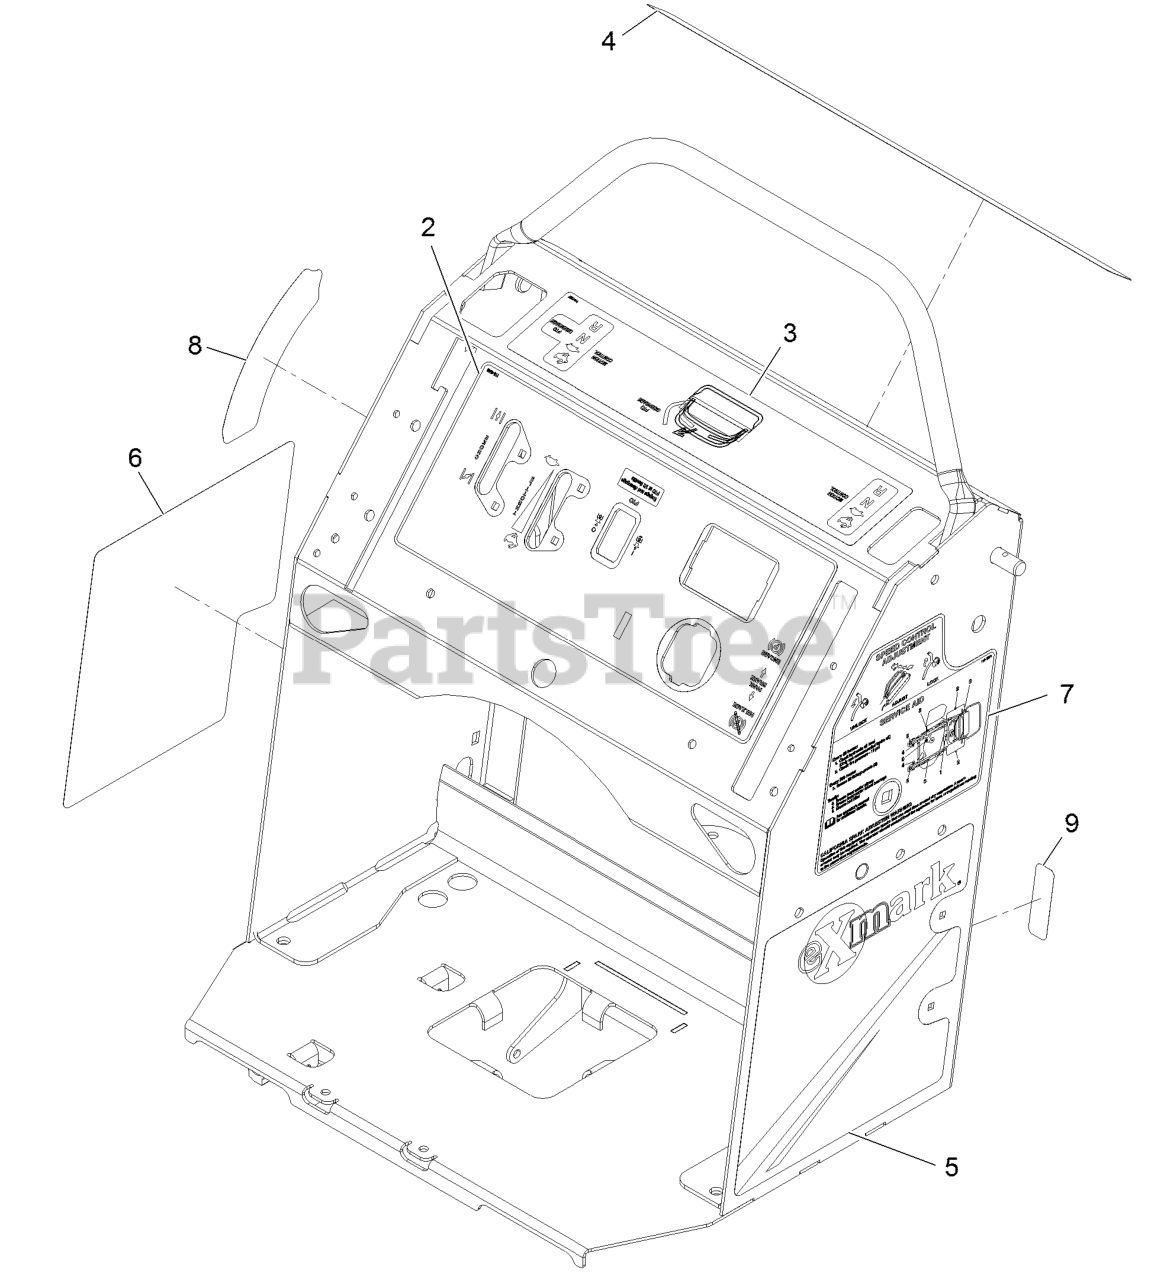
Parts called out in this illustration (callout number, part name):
2	DECAL-CONTROL PANEL
3	DECAL-MOTION CONTROL
4	DECAL-WARNING
5	DECAL-LH PANEL
6	DECAL-RH PANEL
7	DECAL-SERVICE AID
8	DECAL-HEIGHT OF CUT
9	DECAL-FUSE
